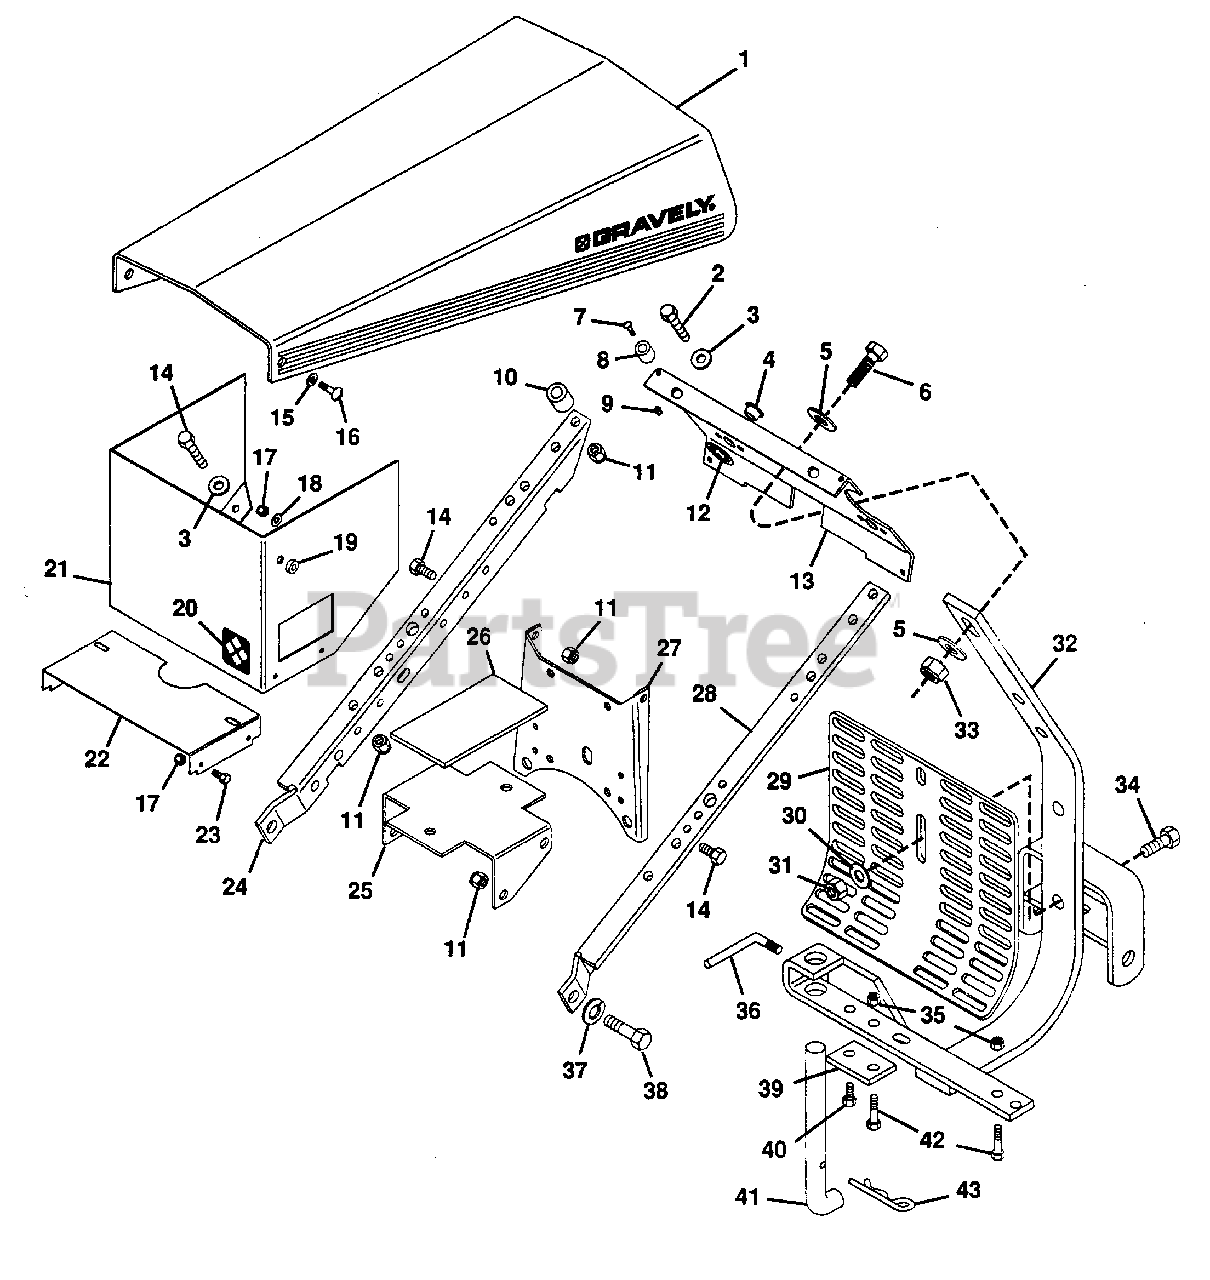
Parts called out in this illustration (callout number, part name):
1	HOOD, SILK SCREEN
2	BOLT, HEX 3/8-16X1.50
3	WASHER, FLAT .406X.812X.065
4	BUSHING, .513X.750X.625
5	WASHER, FLAT .656X1.250X.100
6	BOLT, HEX 5/8-11X2.00
7	SCREW, MACH. 6-32X.625 PHD
8	BUMPER
9	NUT, MACH. LOCK 6-32
10	BUSHING, REVERSE IDLER
11	NUT, LOCK 3/8-16
12	RING, RETAINING
13	PLATE, SILK SCREEN
14	BOLT, HEX 3/8-16X.875
15	WASHER, FLAT .281X.625X.065
16	SCREW, MACH. 1/4-20X1.00 PHD
17	NUT, LOCK 1/4-20
18	WASHER, FLAT .313X.875X.065
19	BUSHING, HOOD
20	DECAL
21	SUPPORT, HOOD
22	BRACKET
23	BOLT, HEX 1/4-20X.625
24	SUPPORT, HANDLEBAR R.H.
25	BRACKET, TANK SUPPORT
26	PAD, GAS TANK
27	BRACKET
28	SUPPORT, HANDLEBAR L.H.
29	GUARD, ENGINE
30	WASHER, FLAT .531X1.250X.100
31	NUT, LOCK 1/2-13
32	WELDMENT, HITCH
33	NUT, LOCK 5/8-11
34	BOLT, HEX 1/2-13X1.50
35	NUT, LOCK 5/16-18
36	HANDLE, ADJUSTING
37	WASHER, LOCK 1/2 REG.
38	BOLT, HEX 1/2-13X1.00
39	BRACKET
40	BOLT, HEX 5/16-18X1.00
41	STAND, KICK
42	BOLT, HEX 5/16-18X2.00
43	PIN, HAIR
NS	DECAL, 16
NS	DECAL, SIDE STRIPE
NS	DECAL, GRAVELY LOGO
NS	DECAL, 8 LEAD
NS	DECAL, PROFESSIONAL
